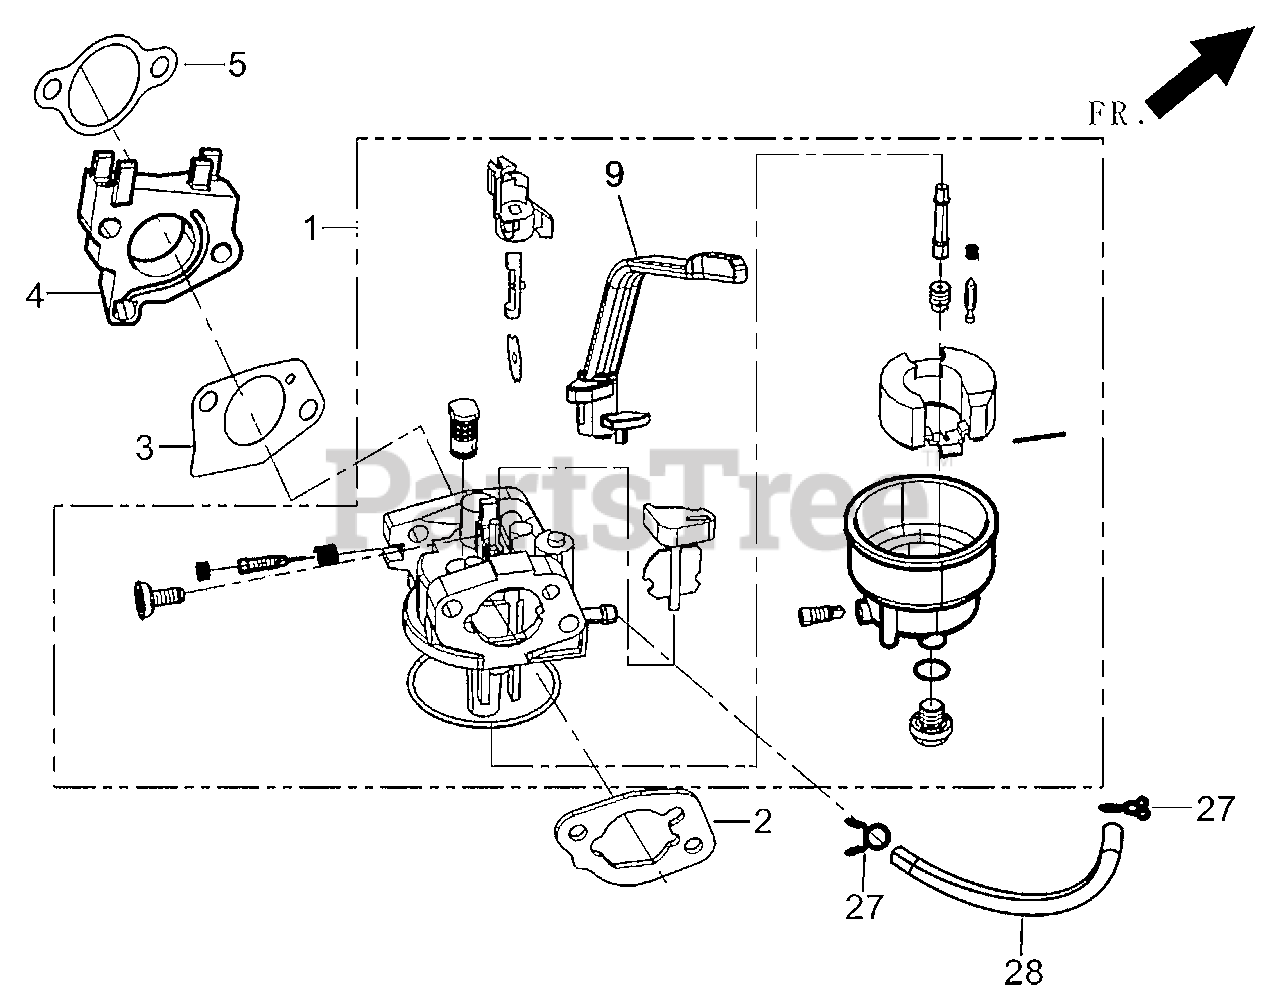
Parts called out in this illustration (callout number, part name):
1	CARBURETOR ASSY.
2	GASKET, AIR CLEANER
3	GASKET, CARBURETOR
4	PLATE, CARBURETOR INSULATOR
5	GASKET, INLET
9	LEVER, PLASTIC CHOKE
27	CLAMP/COLLAR
28	TUBE, FUEL
